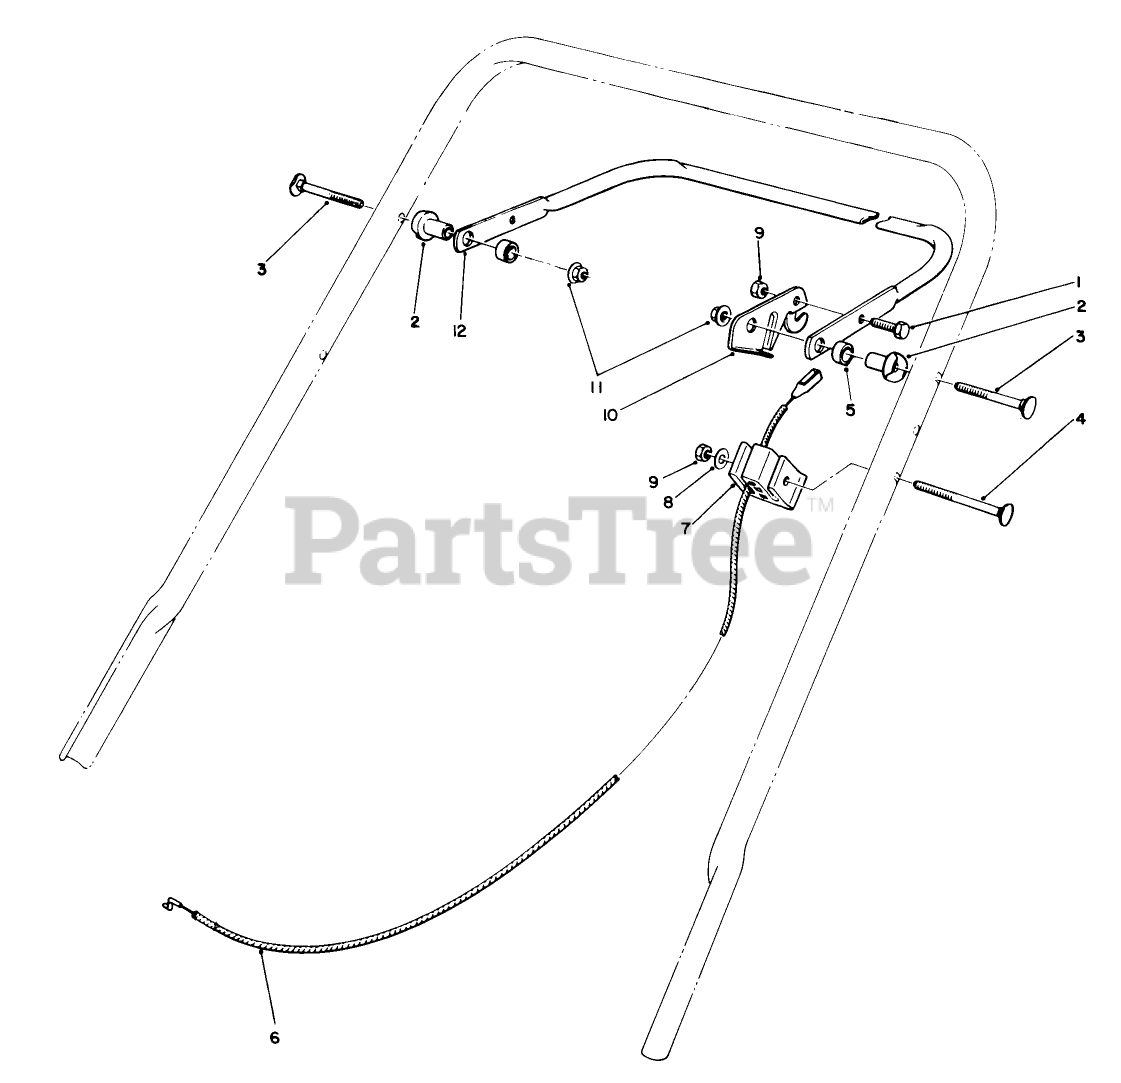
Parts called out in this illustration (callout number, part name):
1	SCREW-HH
2	SPACER-SUPPORT
4	HANDLE SCREW
5	SPACER-NYLON
6	BRAKE CONTROL
7	SUPPORT-CABLE
8	WASHER-FLAT
9	NUT-LOCK, NI
10	CONTROL LEVER
11	NUT-LOCK, NI
